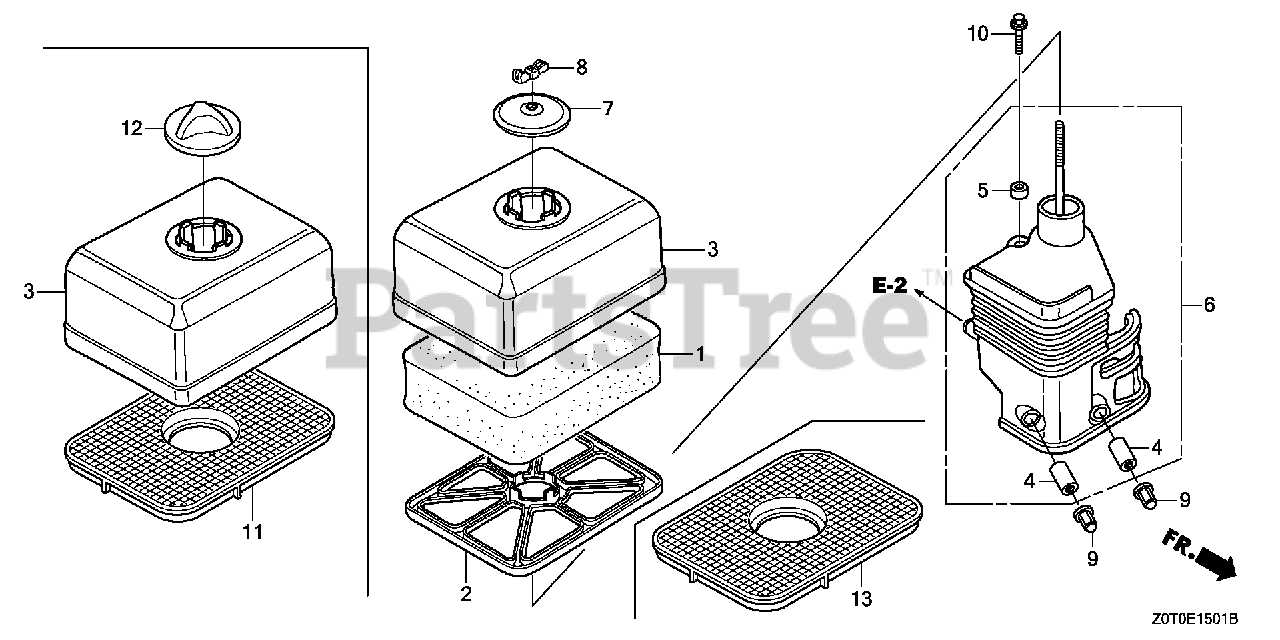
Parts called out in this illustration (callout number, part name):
1	ELEMENT, AIR CLEANER (SEMI-DRY)
2	GRID, AIR CLEANER (SEMI-DRY)
3	COVER, AIR CLEANER (SEMI-DRY)
4	COLLAR, AIR CLEANER
5	COLLAR B, AIR CLEANER
6	ELBOW, AIR CLEANER
7	CAP, CLEANER
8	NUT, TOOL BOX SETTING
9	NUT, FLANGE (6MM)
10	BOLT, FLANGE (6X20)
13	GRID, AIR CLEANER
